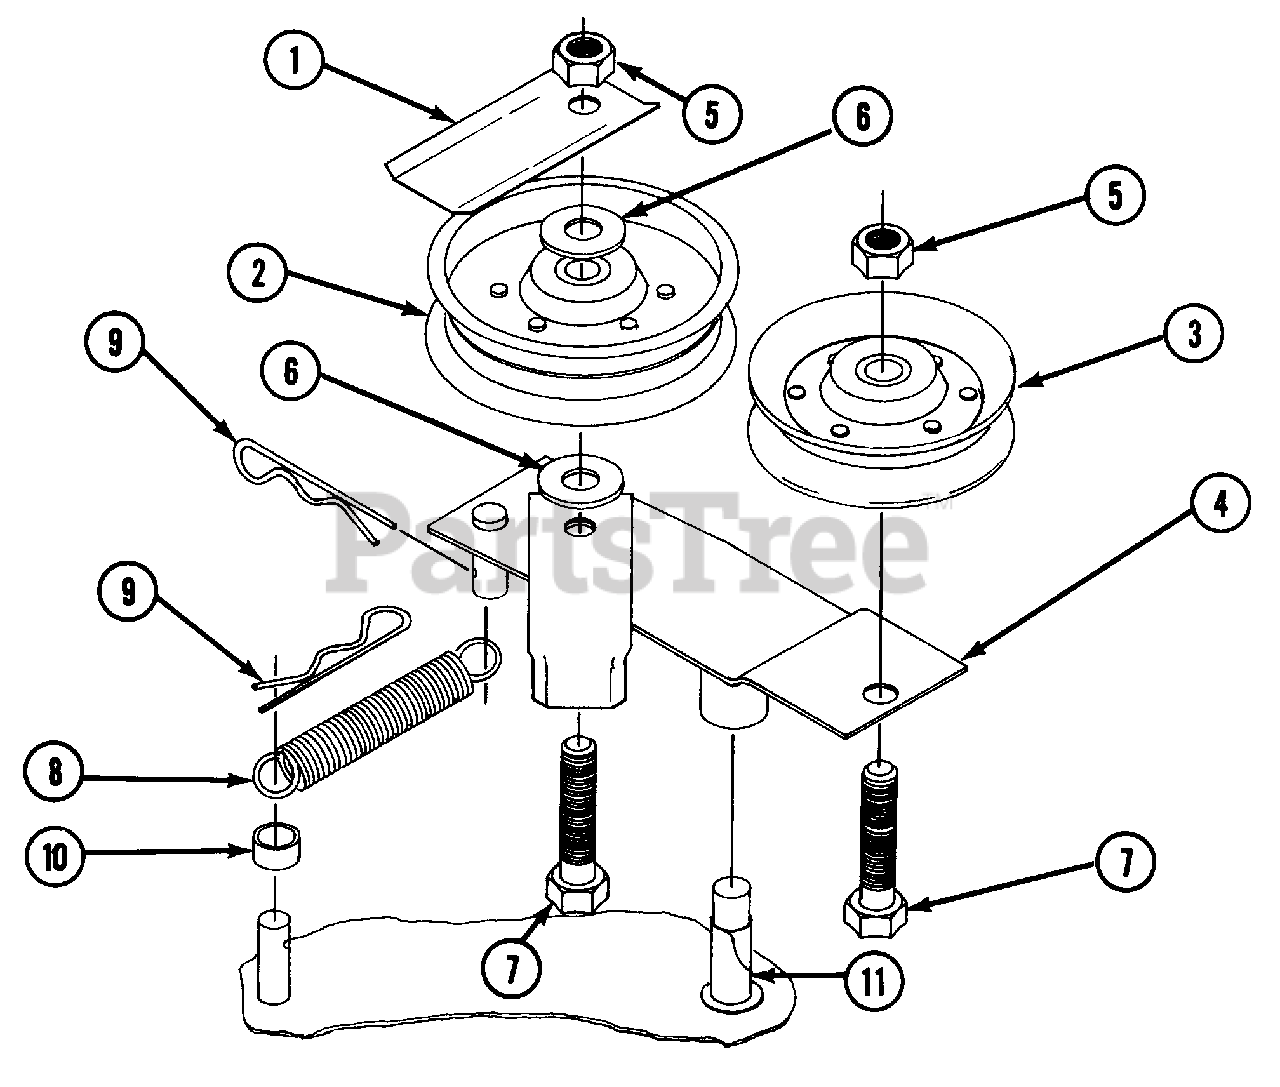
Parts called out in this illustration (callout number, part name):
1	PLATE, BELT STOP
2	PULLEY, FLAT IDLERS 1/2 BORE, 4" OD
3	PULLEY, V IDLER, 1/2 BORE, 4-3/8" OD
4	DOUBLE IDLER WELDMENT, ELECTRIC CLUTCH
5	LOCKNUT, HEX, 1/2-13, W/NYLOC
6	WASHER, 1/2 STD, FLAT
7	CAPSCREW, HEX, 1/2-13 X 2", GRADE 5
8	SPRINGER EXTENSION, 3/4 X 4 OAL
9	PIN, HAIR SPRINGER 1/8 X 2-1/2
10	SPRING SPACER
11	BUSHINGS NYLON, 5/8 BORE
